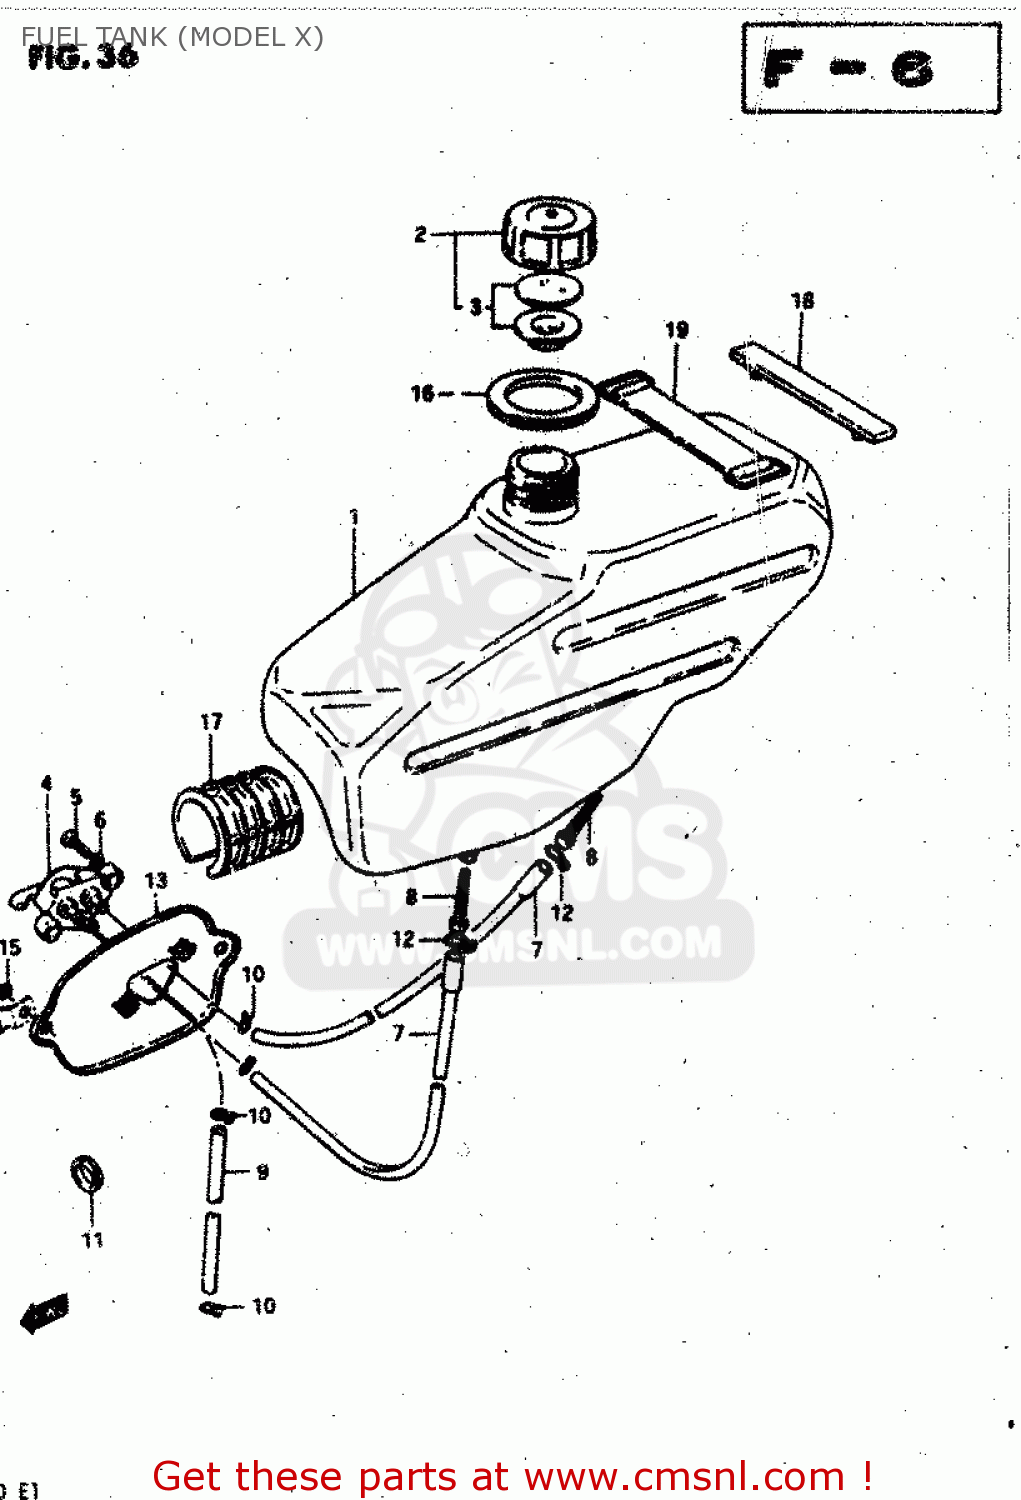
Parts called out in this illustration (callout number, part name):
1	TANK, FUEL
2	CAP SET,FUEL TANK FILLER
3	GASKET,OIL TANK CAP (NAS)
4	COCK ASSY,FUEL
5	SCREW
6	LOCK WASHER
7	HOSE,FUEL
8	FILTER,FUEL
9	HOSE
10	CLIP
11	GROMMET
12	CLIP
13	PLATE, FUEL COCK (ORANGE)
14	SCREW(5X12)
15	LOCK WASHER
16	CUSHION, TANK UPPER
17	CUSHION,FUEL TANK
18	CUSHION, TANK REAR
19	BAND
